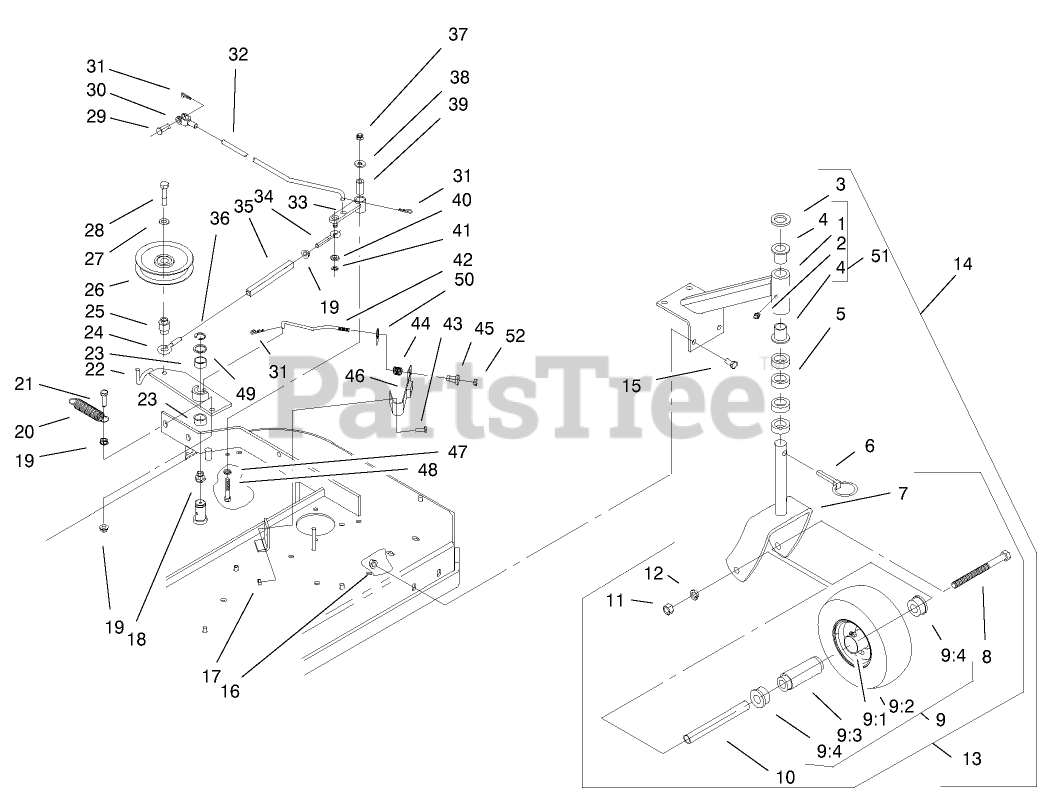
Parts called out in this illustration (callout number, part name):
1	SUPPORT-CASTER
2	FITTING-GREASE
3	WASHER-FLAT
4	BEARING-FLANGED
5	SPACER-CASTER
7	FORK
8	SCREW-HH
9	WHEEL AND TIRE ASM
9:3	BEARING
9:4	BUSHING
10	SPACER
11	NUT-HH
12	WASHER-LOCK
13	CASTER/WHEEL ASM
14	CASTER/MOUNT ASM
15	SCREW-HH
16	NUT-HHF, WHIZ
17	NUT-LOCK, NI
18	FITTING-GREASE
19	NUT-HF
20	SPRING-EXTENSION
21	SCREW-HH
22	ENGAGE ARM ASM W/ BUSHINGS
23	SLEEVE-BEARING
24	EYEBOLT-THREAD, LH
25	BUSHING-ENGAGEMENT
26	PULLEY-IDLER
27	WASHER-BELLEVILLE
28	SCREW-HH
29	PIN-CLEVIS
30	YOKE-ADJUSTABLE
31	PIN-COTTER
32	ARM-ASSIST, LINKAGE
33	ARM-ASSIST
34	EYEBOLT-THREAD, RH
35	BODY-TURNBUCKLE
36	RING-RETAINING, EXT
37	NUT-LOCK, NI
38	WASHER-FLAT
39	TUBE-PIVOT
40	WASHER-PLAIN
41	RING-RETAINING, EXT
42	ROD-BRAKE
43	SCREW-HH
44	SPRING-COMPRESSION
45	SPACER-FLANGED
46	PAD AND SPRING ASM
47	WASHER-SPRING
48	SCREW-HH
49	WASHER-SPINDLE
50	RING-PUSH ON
51	SUPPORT ASM
52	NUT-LOCK, NI
